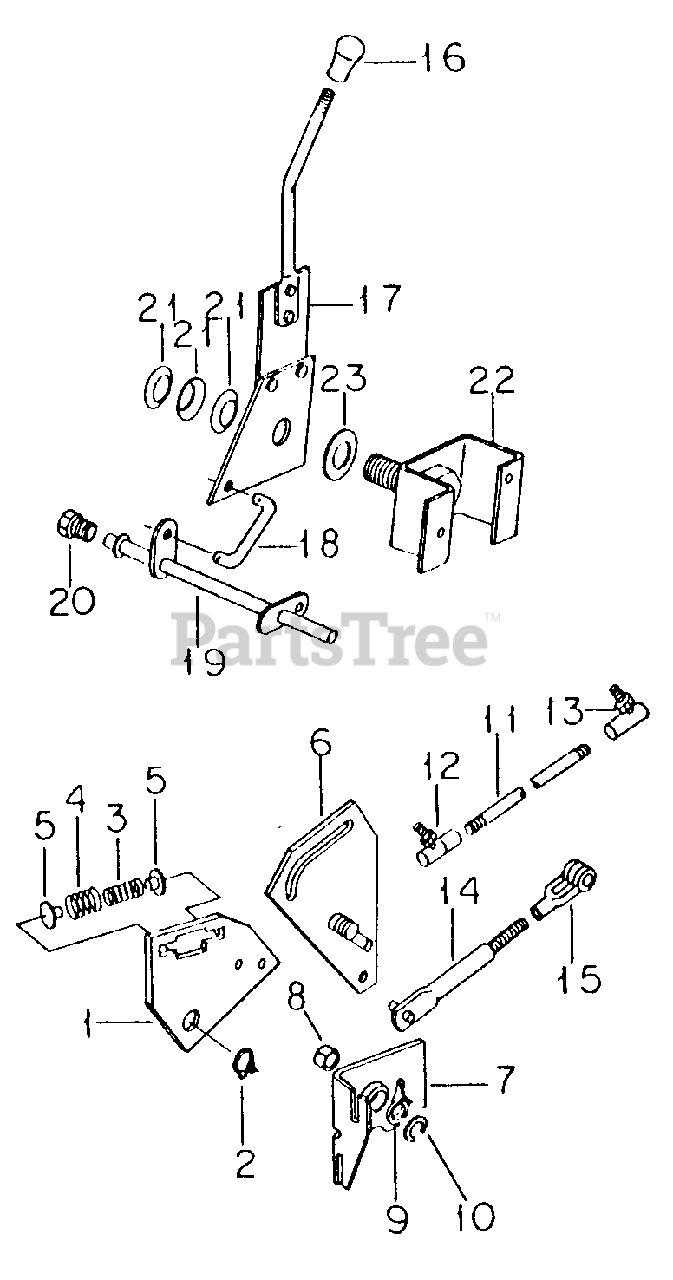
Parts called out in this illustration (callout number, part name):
1	Plate Assy, Damper Spring
2	Ring, Damper Plate Retaining
3	Spring, Damper Light
4	Spring, Damper Heavy
5	Pin, Damper Spring Guide
6	Cam Assy, Control
7	Bracket Assy, Cam Pivot
8	Bushing, Cam Pivot
9	Washer, Cam Retaining
10	Ring, Cam Retaining
11	Stud, Connecting
12	Joint, 5/16-24 X 1-1/2 C-Z RH Thd Ball
13	Joint, 5/16-24 C-Z Ball
14	Rod Assy, Control
15	Clevis, 5/16 Adj Rod End Pin
16	Knob, Control
17	Handle Assy, Control
18	Link, Connecting
19	Rockshaft Assy, Control
20	Bearing, Rockshaft
21	Washer, Belleville Spring
22	Bracket Assy, Control
23	Washer, Friction
